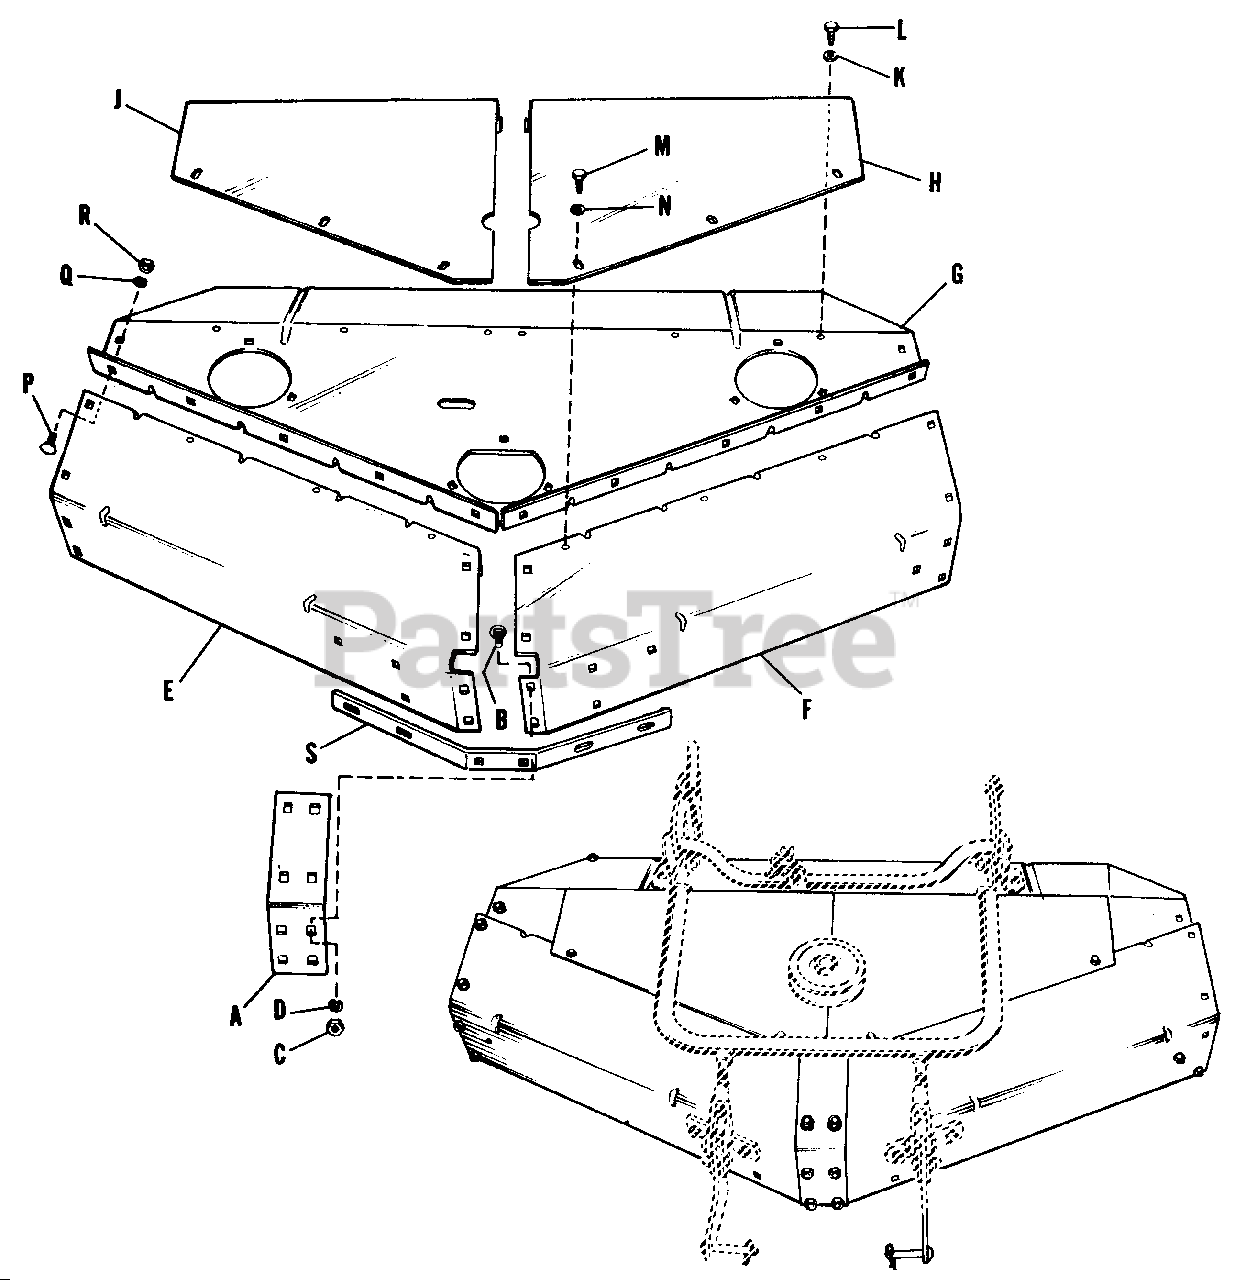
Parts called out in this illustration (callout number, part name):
A	Plate, Front
B	Bolt, Carriage, 3/8"-16 NC x 3/4"
C	Nut, Hex, Full, 3/8"-16 NC
D	Washer, Lock, 3/8"
E	Deck, Front, R.H.
F	Deck, Front, L.H.
G	Deck Housing
H	Cover, L. H.
J	Cover, R. H.
K	Washer, Plain, 3/16"
L	Screw, Recessed Hex, Self Tapping 1/4"-20 NC x 3/8" lg.
M	Screw, Recessed Hex, Self Tapping 1/4"-20 NC x 3/8" lg.
N	Washer, Plain, 3/16"
P	Bolt, Carriage, 3/8"-16 NC x 3/4
Q	Washer, Lock, 3/8"
R	Nut, Hex, Full, 3/8"-16 NC
S	Bar, Reinforcing
